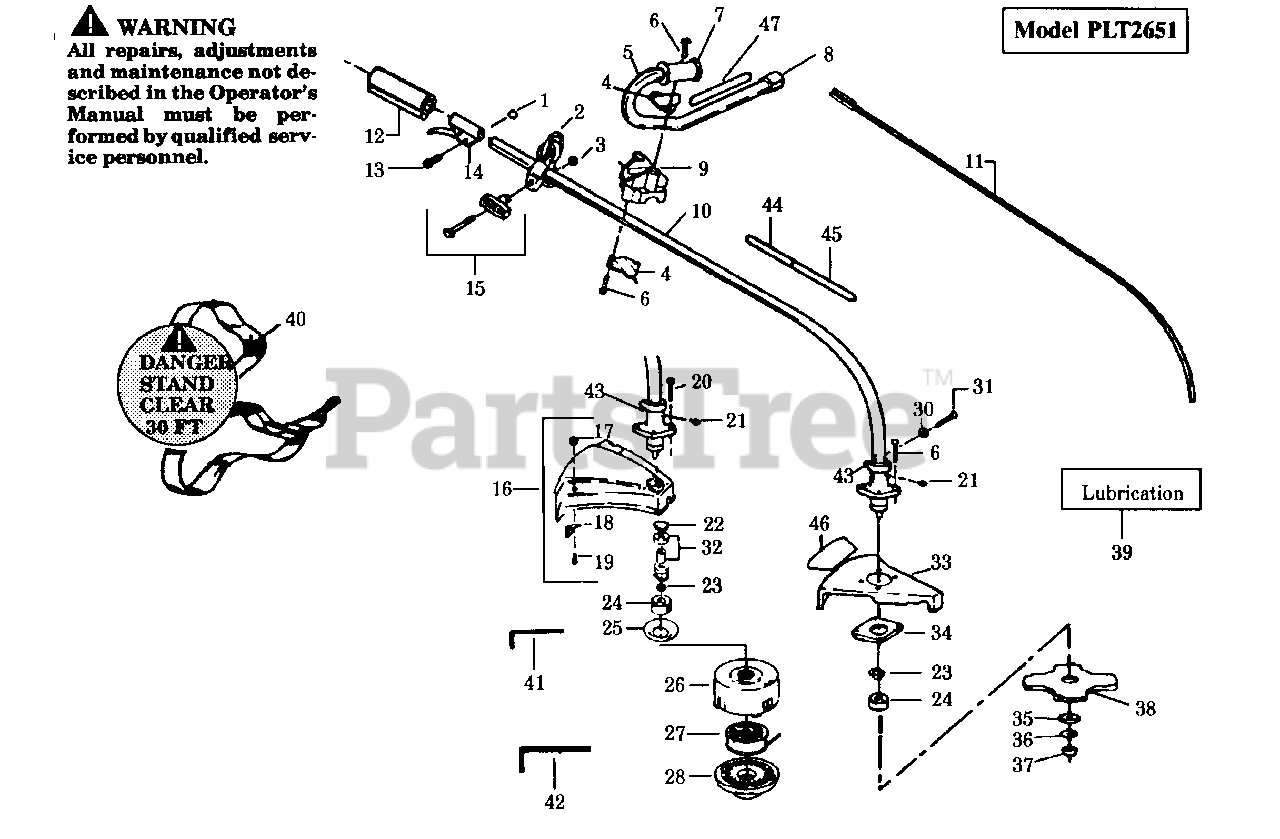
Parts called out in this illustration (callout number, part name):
2	Clamp Harness Ass'y.
4	Handlebar Bracket
5	Handlebar
7	Handlebar Grip
8	Handlebar Cap
9	Handlebar Clamp
10	Drive Shaft Housing
11	Drive Shaft
12	Drive Shaft Grip
14	Throttle Lever Ass'y.
15	"T" Handle Kit
16	Shield Kit Ass'y.
17	Locknut
18	Line Limiter
20	Screw
22	Retaining Ring
24	Dust Cup
25	Grass Washer
26	Hub Ass'y.
27	Spool w/Line
32	Bearing & Spacer Kit
33	Shield
34	Shield Retention Plate
36	Washer
38	Weed Blade
39	Shaft Lubrication
40	Shoulder Strap
41	Hex Wrench (5/32)
42	Hex Wrench (3/16)
43	Bearing Housing Ass'y.
44	Decal-Shaft Warning (Upper)
45	Decal-Shaft Warning (Lower)
46	Decal-Blade Direction (Not a serviceable part)
47	Decal-Handlebar
